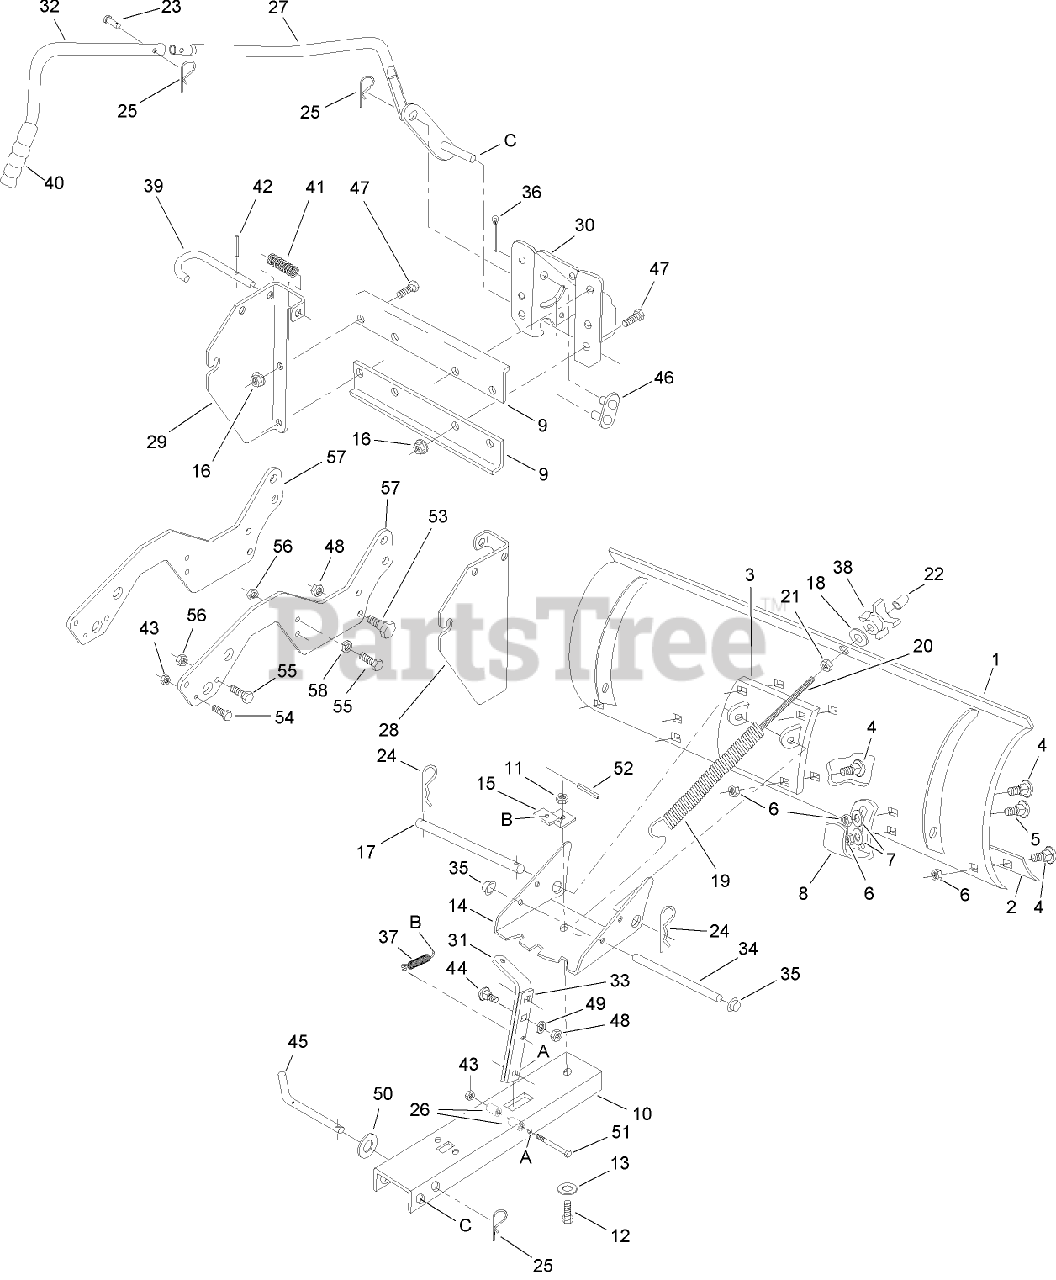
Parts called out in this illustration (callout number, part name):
2	PLATE-WEAR
3	REINFORCEMENT PLATE ASM
4	BOLT-CARR
5	BOLT-CARR
6	NUT-LOCK
7	WASHER
8	SKID-SHOE
9	BRACKET-SUPPORT, ANGLE
10	CHANNEL-PUSH
11	NUT-LOCK
12	BOLT-PIVOT, SPECIAL
13	WASHER-FLAT
14	PLATE-PIVOT
15	BRACKET-MOUNTING, SPRING
16	NUT-LOCK, FLANGED
17	SHAFT-PIVOT
18	WASHER-FLAT
19	SPRING-ADJUST, BLADE
20	SCREW-HH
21	NUT-HEX
22	CAP-PLASTIC
23	PIN-CLEVIS, LIFT HANDLE
24	PIN-HAIR
25	PIN-QUICK ATTACH
26	SPACER
27	LOWER LIFT HANDLE ASM
28	HITCH-BRACKET, RH
29	HITCH-BRACKET, LH
30	BRACKET-SUPPORT, PIVOT
31	BAR-LOCK, ANGLE (LONG)
32	HANDLE-LIFT, UPPER
33	BAR-LOCK, ANGLE (SHORT)
34	ROD-MOUNT, SPRING
35	NUT-PUSH
36	PIN-COTTER
37	SPRING-LOCK, ANGLE
39	PIN-ATACHMENT
40	GRIP-HANDLE
41	SPRING-COMPRESSION
42	PIN-SPRING
43	NUT-LOCK, FLANGE
44	BOLT-CARR
45	SHAFT-CHANNEL, PIVOT
46	LINK-LIFT
47	SCREW-HH
48	NUT-LOCK
49	WASHER-LOCK
50	WASHER
52	PIN-SPRING
53	BOLT-SHOULDER
54	SCREW-HH
55	SCREW-HH
56	NUT-NYLOCK
57	BRACKET-FRAME
58	WASHER-LOCK
